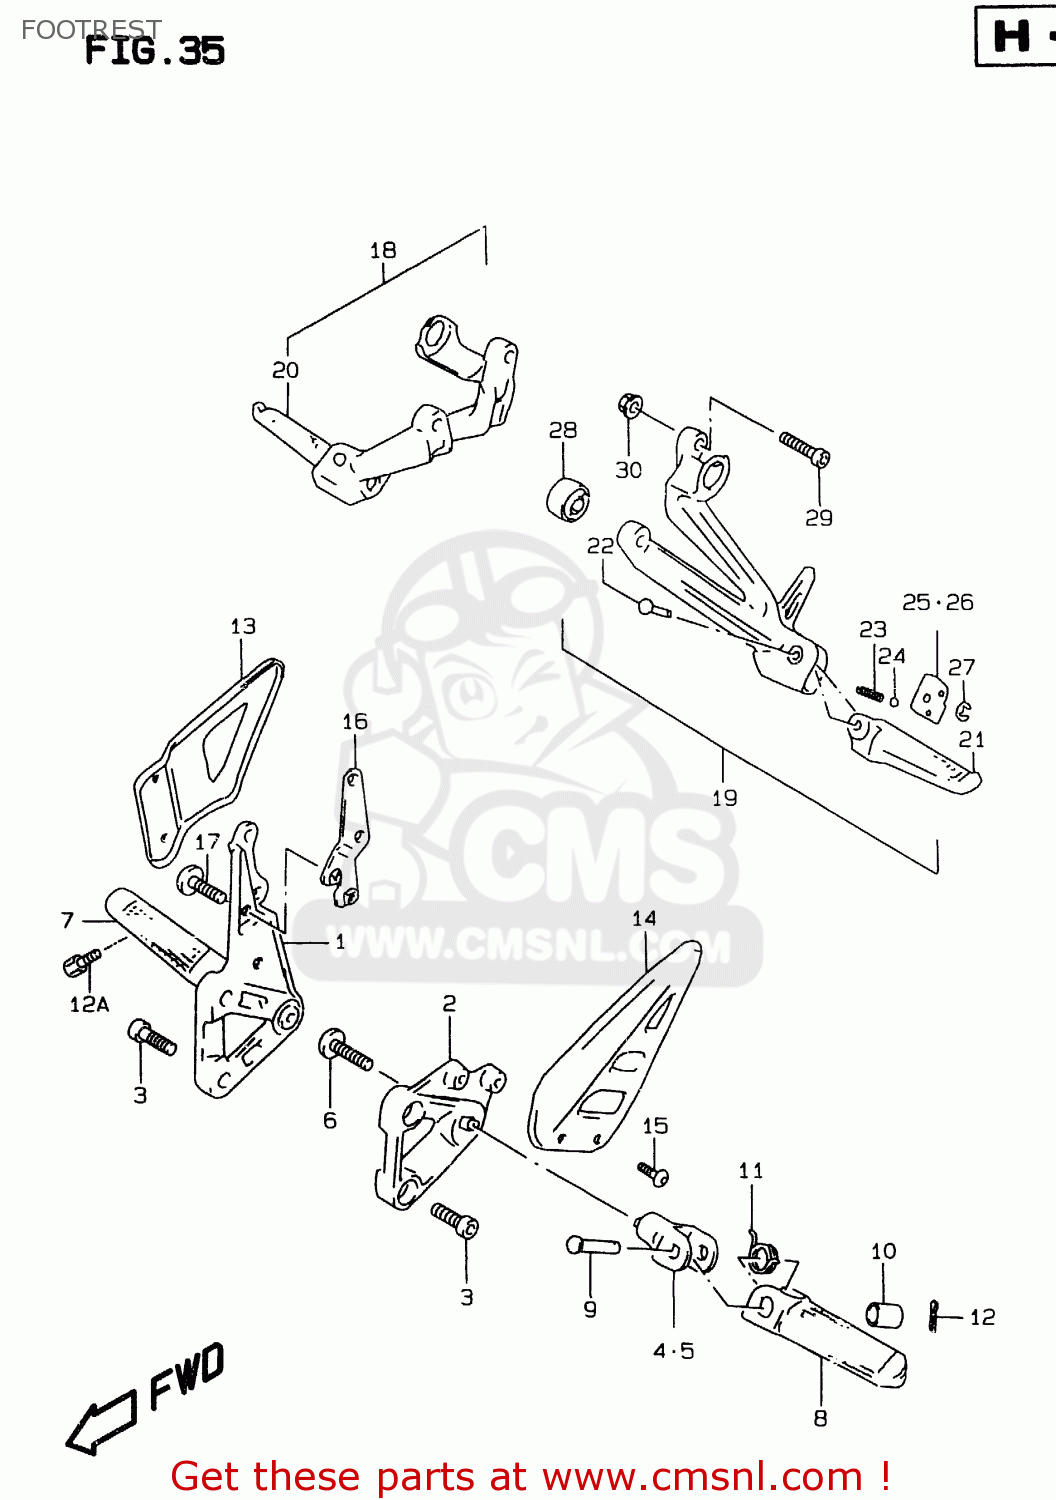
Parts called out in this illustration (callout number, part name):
1	BRACKET,FR FOOTREST,R
2	BRACKET,FR FOOTREST,L
3	BOLT
4	HOLDER,FOOTREST,R
5	HOLDER,FOOTREST,L
6	BOLT(10X28)
7	BAR,FOOTREST,RIGHT
8	BAR,FOOTREST,LEFT
9	PIN
10	SPACER(8.1X12X22)
11	SPRING
12	PIN 20X15
12A	BOLT,BANK SENSOR
13	GUARD,FR FOOTREST,R
14	GUARD,FR FOOTREST,L
15	SCREW(5X10)
16	REINF,FOOTREST BRACKET,R
17	SCREW(6X16)
18	FOOTREST ASSY,PILLION,R
19	FOOTREST ASSY,PILLION,L
20	BAR,PILLION FOOTREST,RIGHT
21	BAR,PILLION FOOTREST,LEFT
22	PIN
23	SPRING
24	BALL
25	PLATE,PILLION,RIGHT
26	PLATE,PILLION,LEFT
27	E-RING
28	BUSH
29	BOLT
30	NUT
